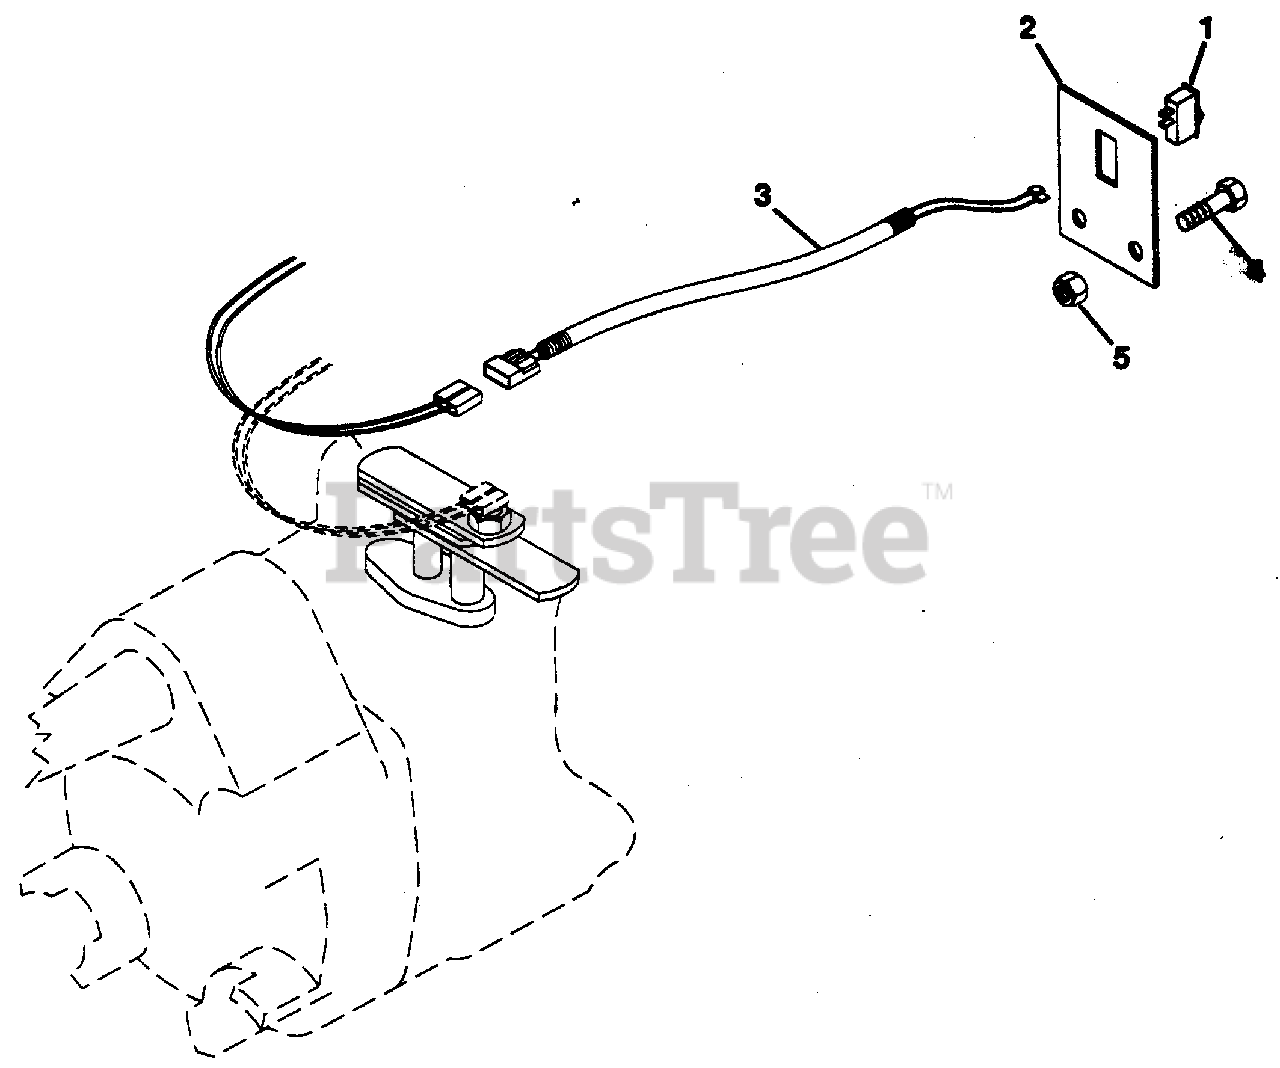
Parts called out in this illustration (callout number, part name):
1	Headlamp, 3x5 Halogen
2	Terminal, Male
3	Grommet
4	Washer, Flat .531x1.000x.063
5	Switch, Light
6	Terminal, Female 1-Wire 16 Ga.
7	Wire, #1
8	Terminal, Female
9	Terminal, Ring Tongue
10	Wire, #2
11	Terminal, Female 2-Wire
12	Bolt, Hex 1/4-20x1.00
13	Bracket, Cab Top
14	Bracket, Cab Bottom
15	Nut, Lock 1/4-20
NS	Tie, Cable
